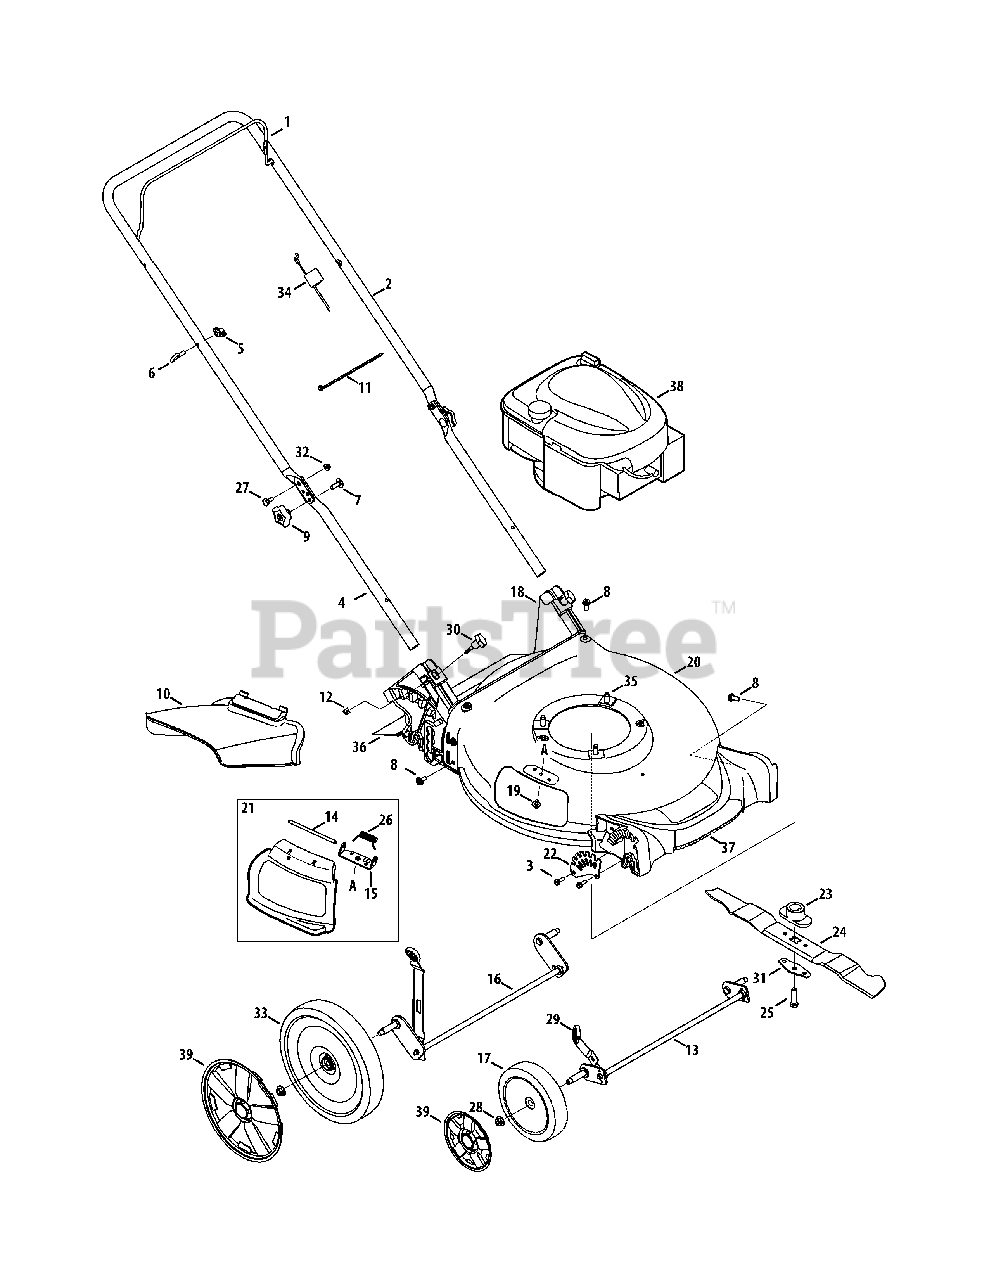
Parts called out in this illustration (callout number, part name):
1	Blade Control
2	Upper Handle
3	Screw, 1/4-15 x .750
4	Lower Handle
5	Wing Nut
6	Rope Guide
7	Carriage Screw ,5/16-18
8	Screw, 5/16-14 x .750
9	Hand Knob
10	Side Chute
11	Cable Tie
12	Nut, Sq., 1/4-20
13	Front Axle Assembly
14	Hinge Pin
15	Chute Deflector Bracket
16	Rear Axle Assembly
17	Wheel, 7 x 2
18	Rear Baffle
19	Screw, 1/4-20 x .500
20	Deck - 21"
21	Hinged Mulch Plug Assembly
22	Front Height Adjuster Plate
23	Blade Adapter
24	Mulching Blade
25	Screw , 3/8-24 x 1.50
26	Torsion Spring
27	Sldr. Screw, .375 x .126 x 1/4-20
28	Flange Lock Nut, 3/8-16
29	Adjustment Lever Knob
30	Wing Nut
31	Blade Bell Support
32	Nut, Flange Lock, 1/4-20
33	Wheel, 11 x 2
34	Control Cable
35	TT Sems Screw, 3/8-16 x 1.0
36	Trail shield
37	Front Cover
38	Engine 126T02-0863-B1
39	Hub Cap - Front
39	Hub Cap - Rear
